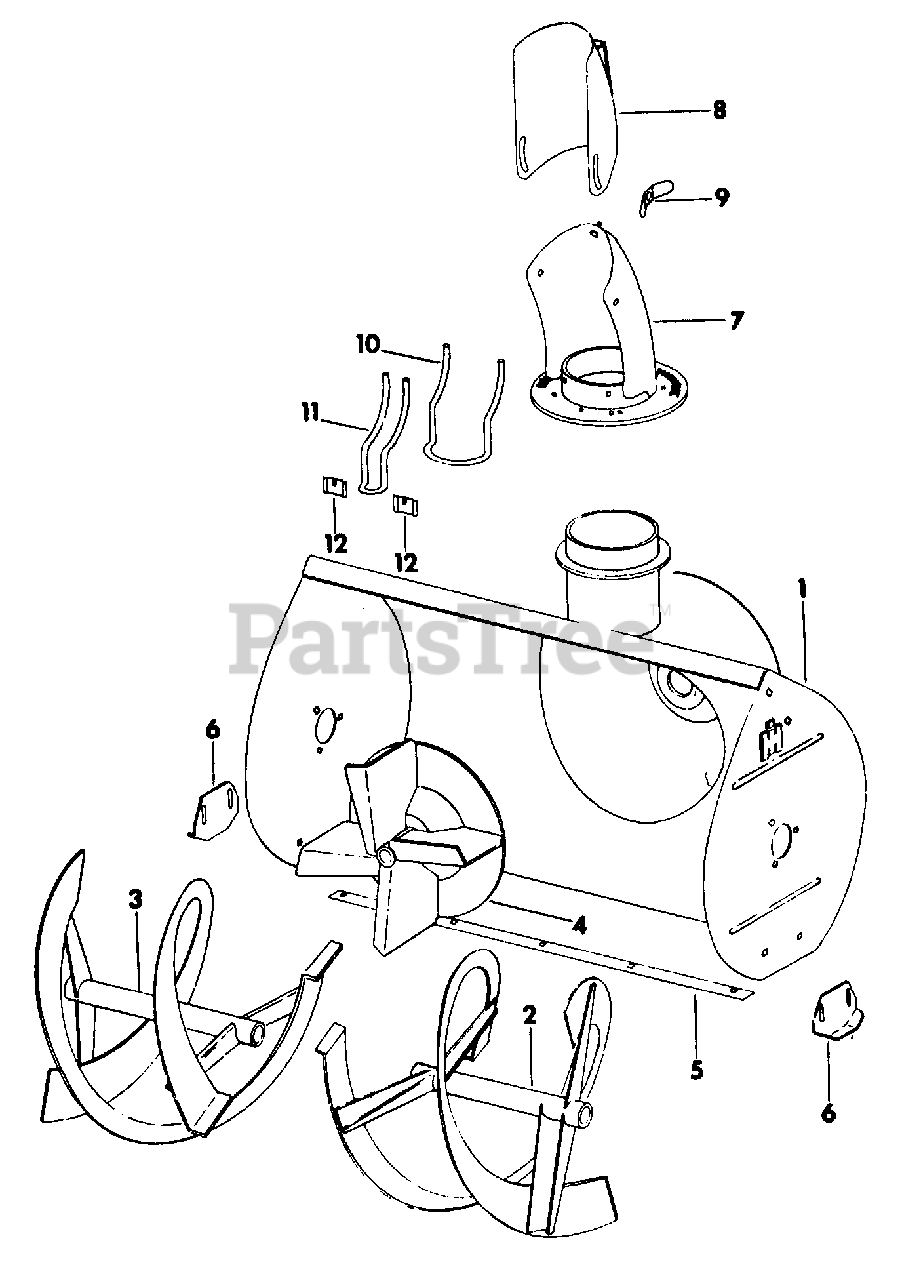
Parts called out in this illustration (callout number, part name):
1	HOUSING, WELDED
1	HOUSING
5	BLADE, SCRAPER
8	CAP W/CAUTION PRODUCT GRAPHIC, IH-73235-C2, DEFLECTOR
10	ROD, DEFLECTOR SIDE
11	ROD, DEFLECTOR CENTER
12	CLAMP, DEFLECTOR
